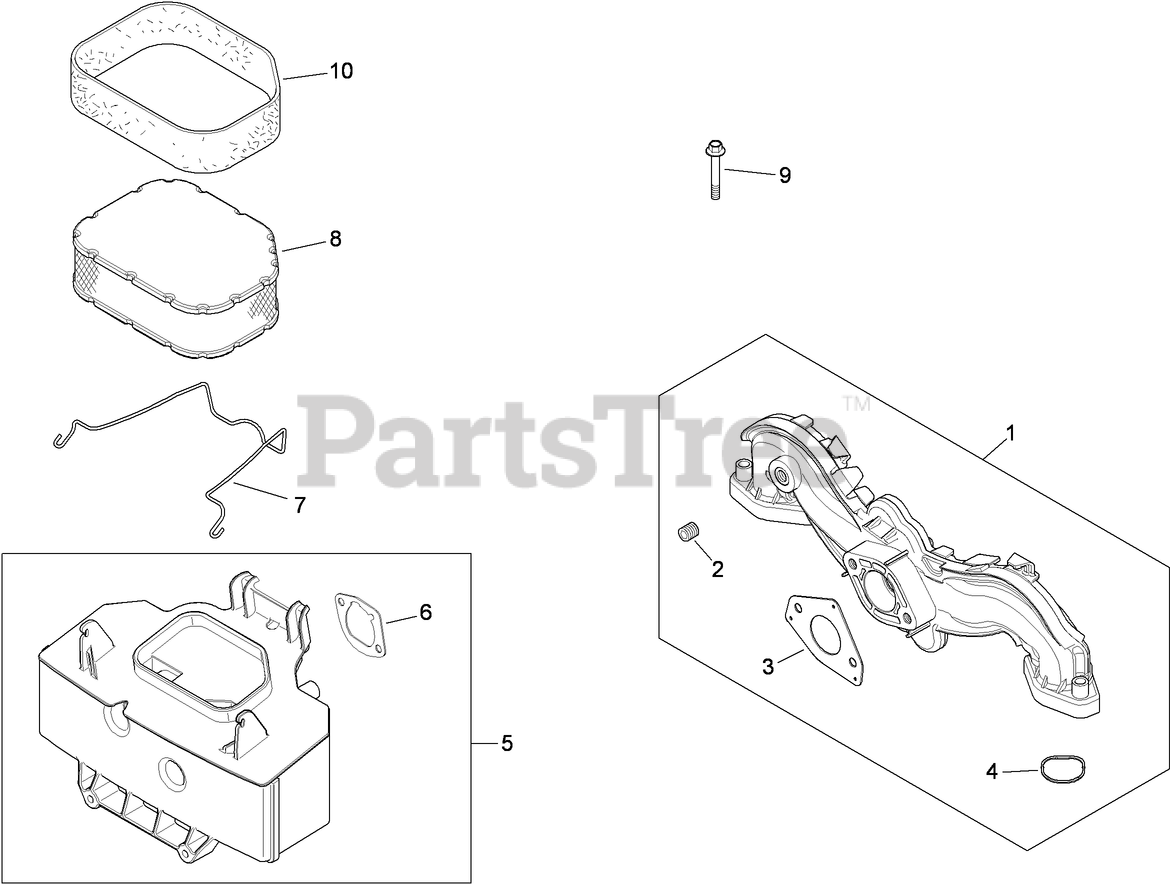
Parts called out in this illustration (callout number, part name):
1	MANIFOLD, INTAKE (INCLUDES 2,3)
2	PLUG-PIPE, COUNTERSUNK (1/8)
3	GASKET-CARBURETOR
4	O-RING
5	AIR CLEANER BASE KIT (INCLUDES 5-6)
6	GASKET-BASE, AIR CLEANER
7	LATCH-ELEMENT, AIR CLEANER
8	ELEMENT-FILTER, AIR
9	SCREW-FLANGE (M6X1.0X40)
10	ELEMENT-CLEANER, PRE
